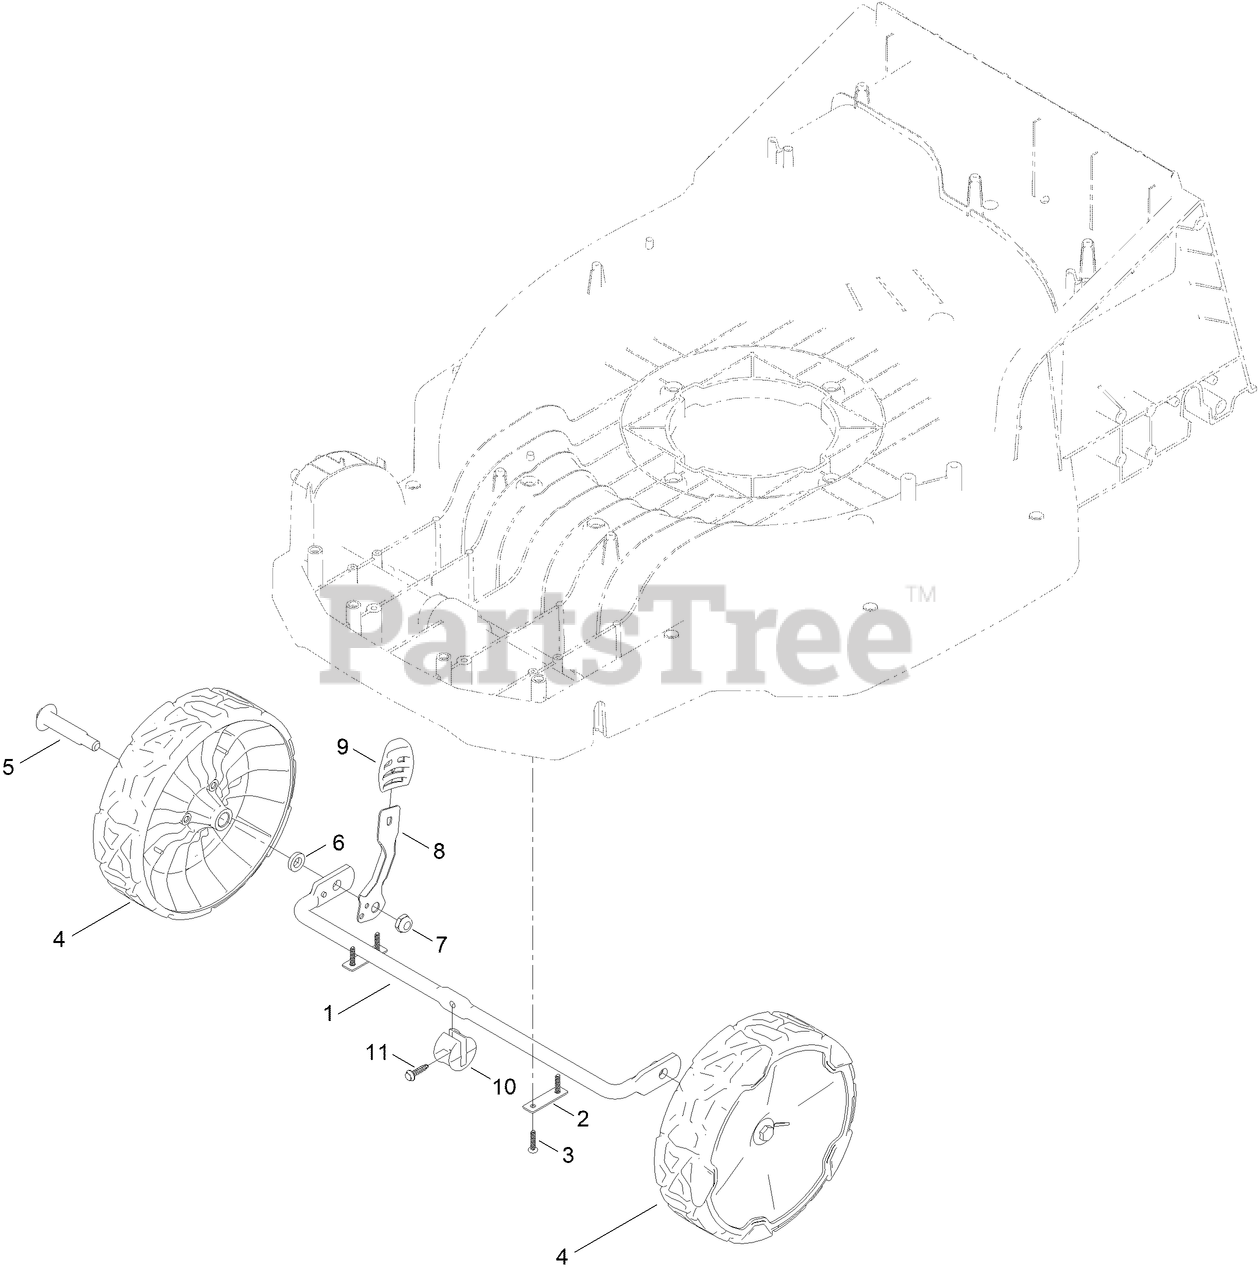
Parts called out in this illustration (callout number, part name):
1	AXLE-FRONT
2	STRAP-AXLE
3	SCREW-PPH
4	ASM-8" WHEEL, IDLER
5	BOLT-SHOULDER
6	WASHER-WHEEL BOLT
7	NUT-HEX
8	ARM-SPRING
9	KNOB-LEVER, HOC
10	STOP-AXLE
11	SCREW-HWH
